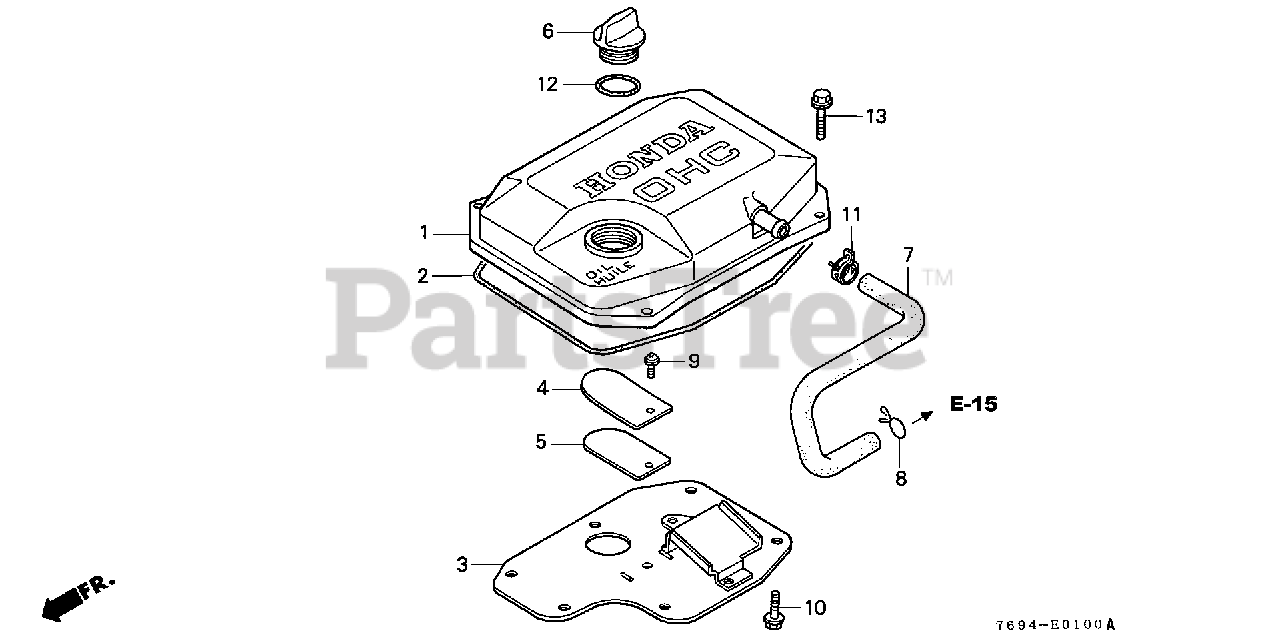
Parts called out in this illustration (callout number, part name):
1	COVER, CYLINDER HEAD
2	GASKET, HEAD COVER
3	COVER, BREATHER
4	STOPPER, VALVE
5	PLATE, VALVE
6	CAP, OIL (GRAY)
6	CAP, OIL
7	TUBE D, BREATHER
8	CLIP, BREATHER TUBE
9	SCREW-WASHER (5X8)
10	BOLT, FLANGE (6X10)
11	CLAMP, CANISTER HOSE
12	O-RING (26X2.7)
13	BOLT, FLANGE (6X25)
